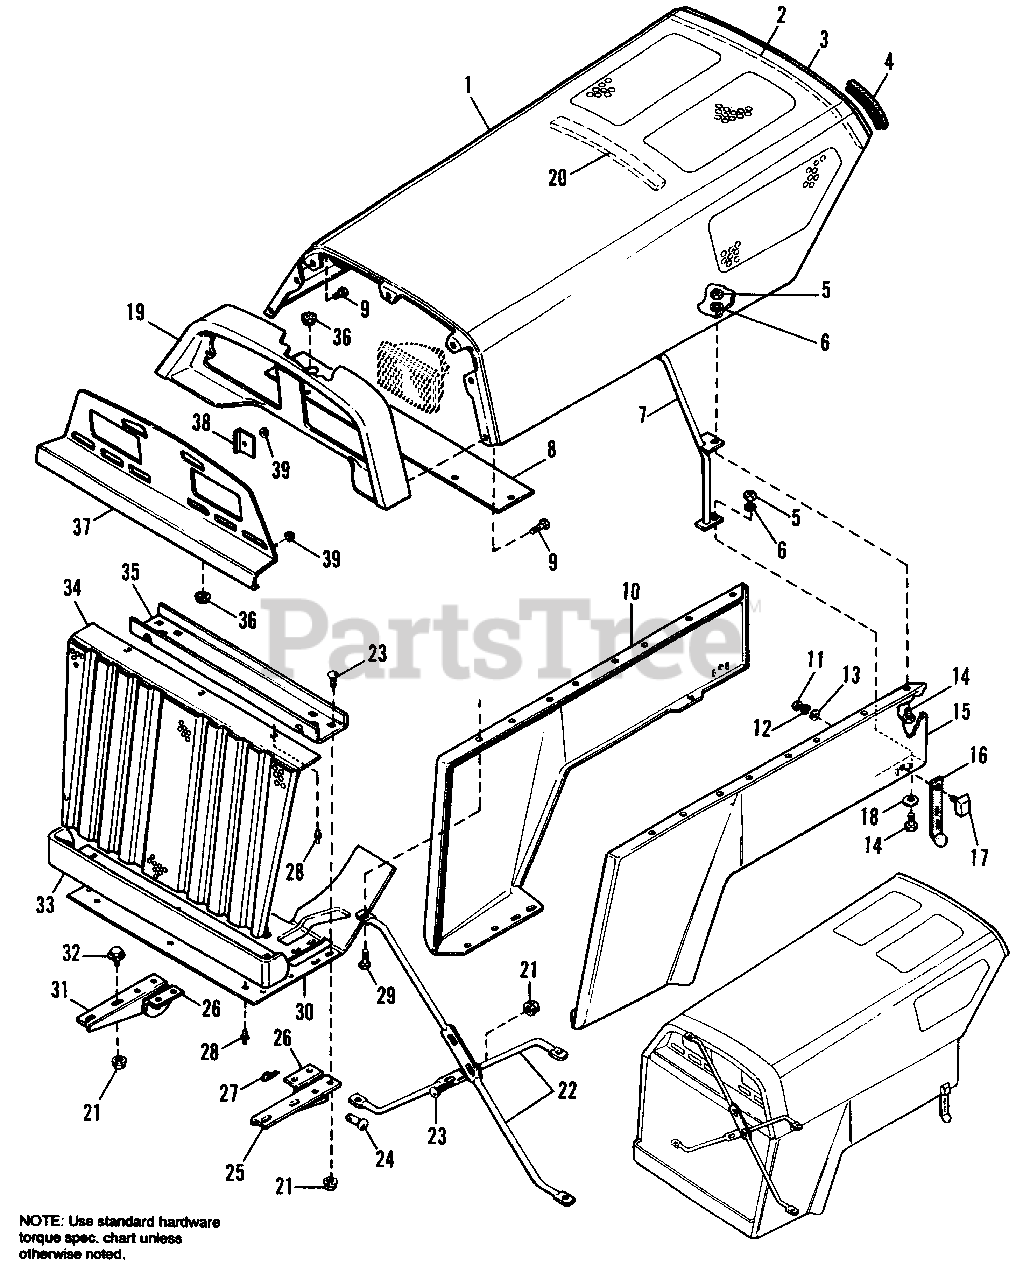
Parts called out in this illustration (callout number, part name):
2	SEAL, Hood, Rear
3	DECAL, Hood Rear
4	MOLDING, Hood
5	NUT, Hex, 1/4-20
6	LOCKWASHER, 1/4
7	SUPPORT ROD ASSY., Hood
8	SHIELD, Muffler
9	SCREW, Hex, Taptite, 1/4-20 x 1/2
10	PANEL Side, R.H.
11	NUT, Hex, #10-24
12	LOCKWASHER, #10
13	WASHER, 13/64 ID x 3/4
14	CAPSCREW, Hex Hd., 1/4-20 x 1/2
15	PANEL, Side, L.H.
16	STRAP, Hood
17	COVER ASSY., Hood Strap
18	WASHER, Plain, 1/4 x 5/8 x 3/64
19	FRAME, Headlamps
20	SEAL, Hood Support
21	NUT, Hex, Flange Whizlock, 1/4-20
22	BRACE, Hood, Front
23	BOLT, Carriage, 1/4-20 x 3/4
24	PIN, Lock (Clevis)
25	HINGE, Hood, Outer, L.H.
26	HINGE, Hood, Inner
27	PIN, Quick, 3/32 x 1-7/8
28	RIVET, Pop, 3/16
29	SCREW, Hex, Thd. Form, #14-3/4
30	SHIELD, Heat
31	HINGE, Hood, Outer, R.H.
32	SCREW, Hex, R. Whiz Lock, 1/4-20 x 3/4
33	BUMPER ASSY.
34	SCREEN ASSY., Grille
35	SUPPORT, Stop, Hood
36	BUSHING, Universal
37	HEADLAMP INSERT ASSY.
38	CLIP, Headlamps, Mounting
39	PALNUT, Hex, Lock, #10-24
